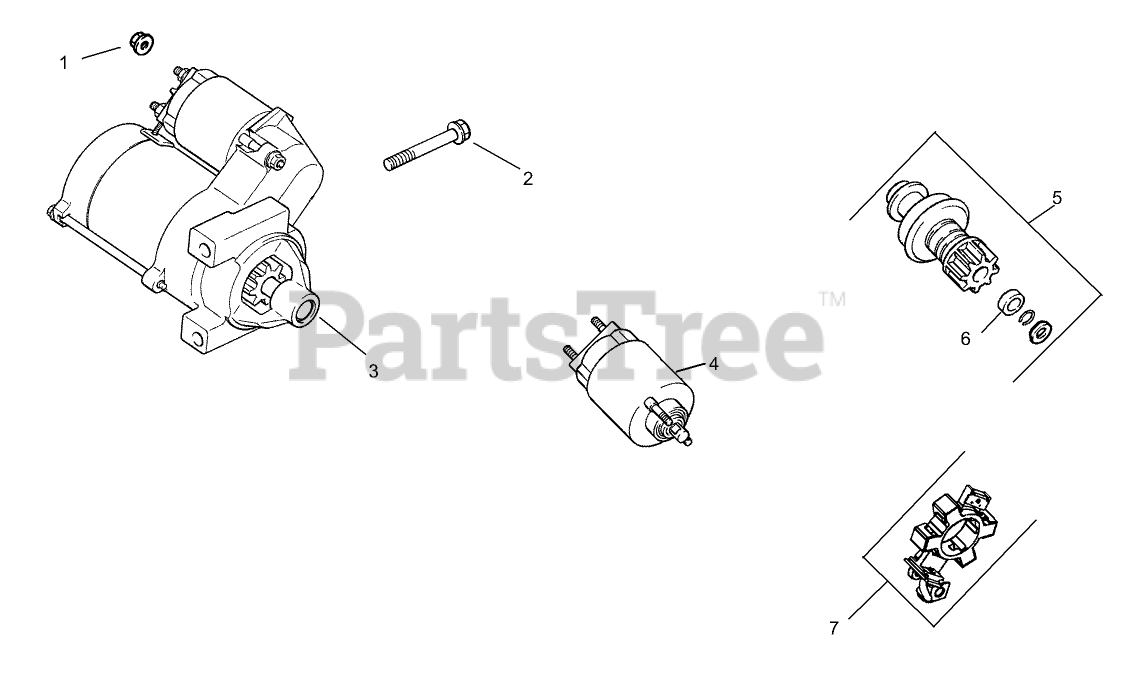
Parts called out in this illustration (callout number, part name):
1	NUT-FLANGE (M8X1.25)
2	SCREW-FLG (M8X1.25X80)
3	Starter, solenoid shift asm (Includes 4-7)
4	Solenoid Kit
5	Kit, pinion drive (Includes 6)
6	RING-RETAINING
7	BRUSH HOLDER KIT
